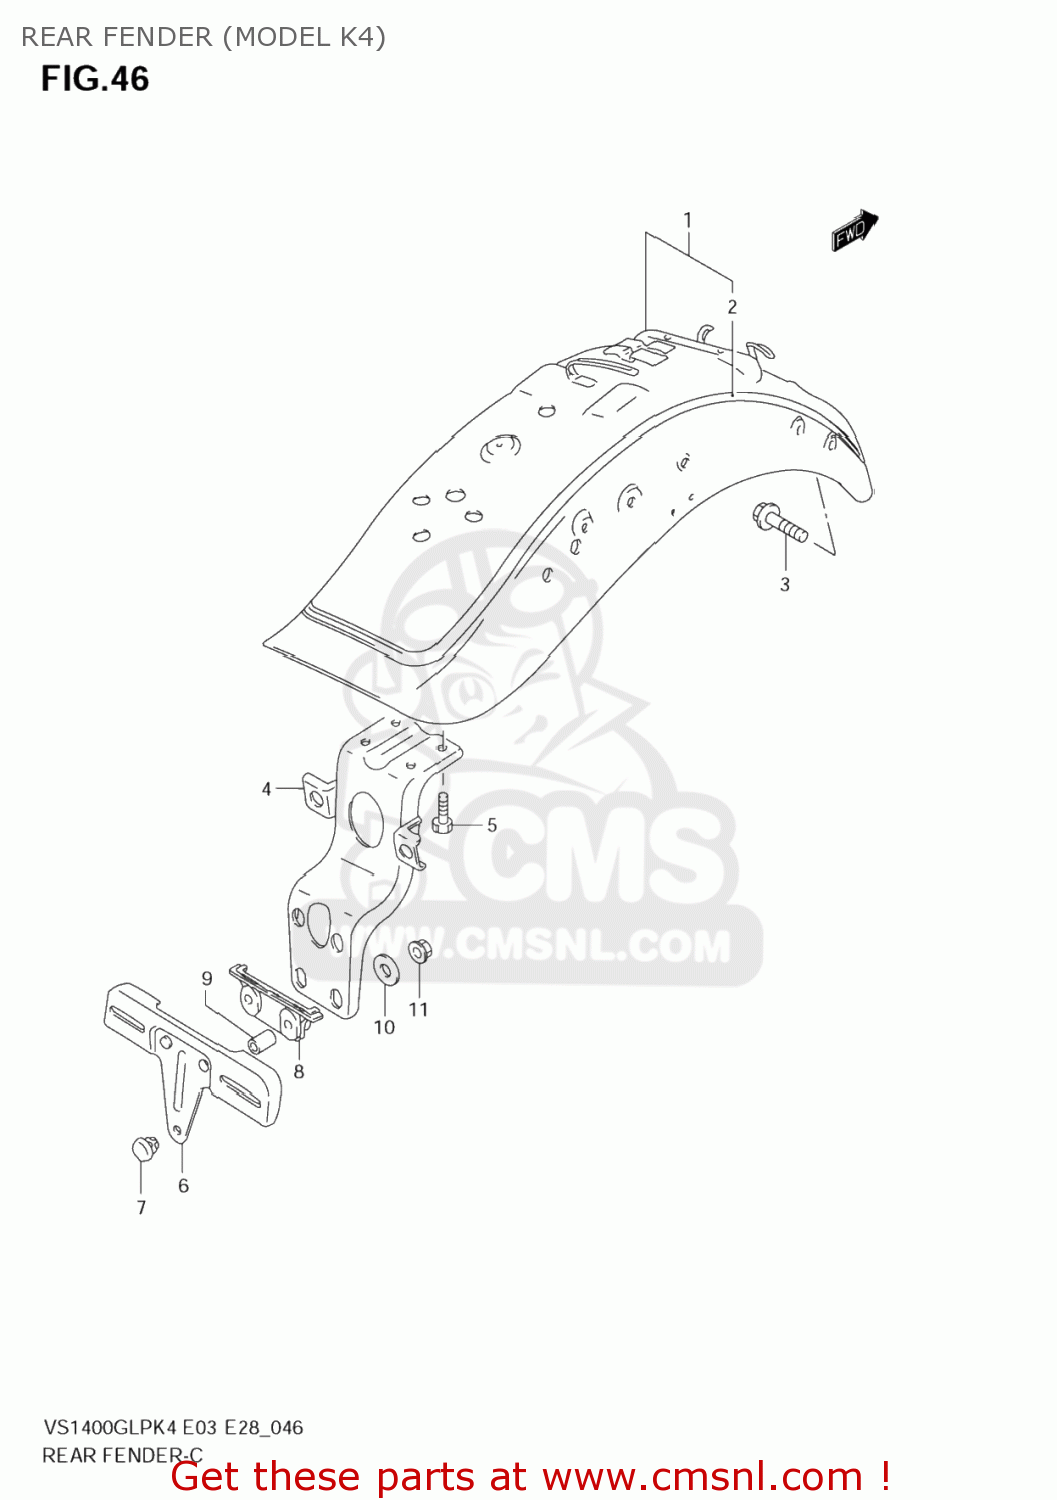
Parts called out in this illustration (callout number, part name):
1	FENDER ASSY,RR
2	TAPE SET,RR FENDER STRIPING
3	BOLT
4	BRACKET,RR COMBINATION LAMP
5	BOLT
6	PLATE,REAR LICENSE
7	CUSHION
8	CUSHION,RR LICENSE PLATE
9	SPACER(5.5X8X14.3)
10	WASHER(5.5X20X1.2)
11	NUT
